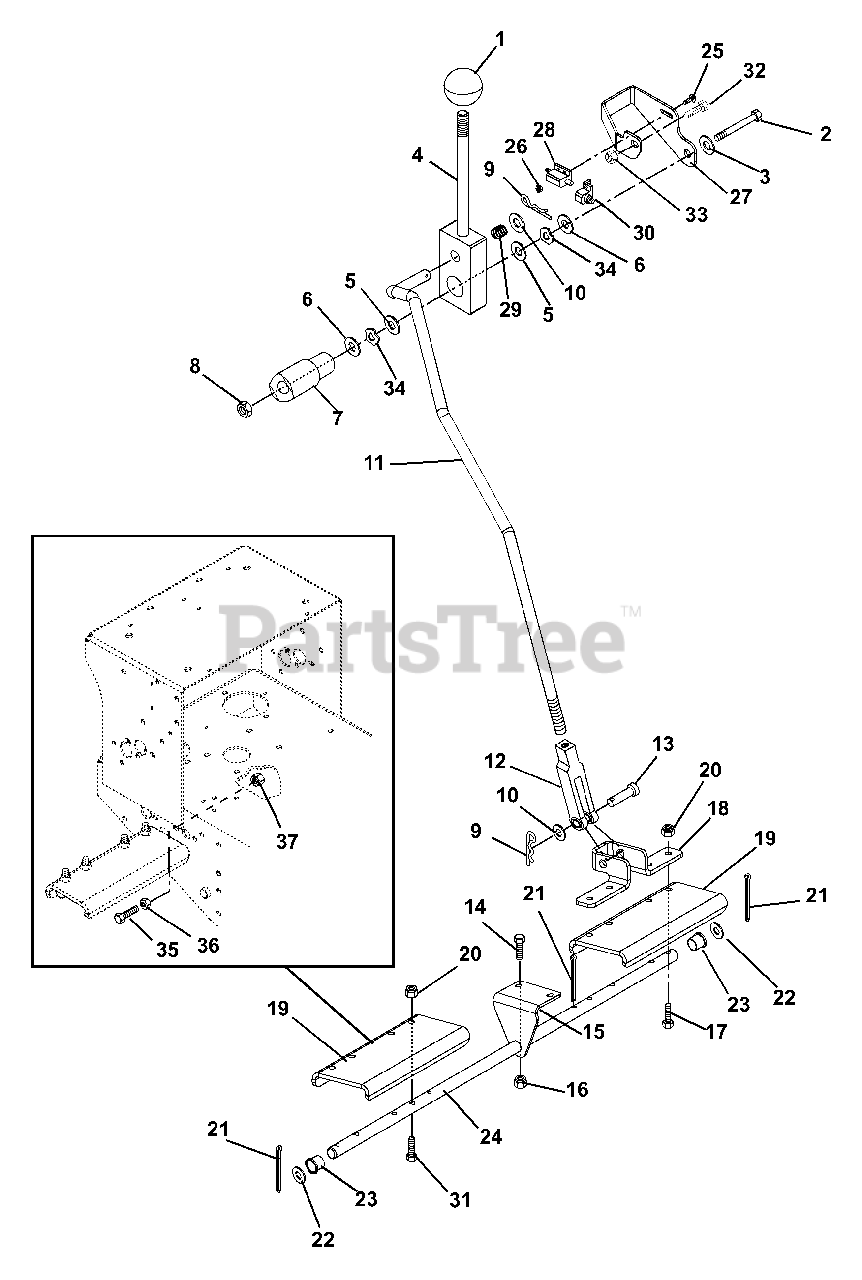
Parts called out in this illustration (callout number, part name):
1	KNOB,BALL -BLACK 1.47" .375-16
2	BLT-HEX .44-14X4.5 GR5 YWZC
3	@WSHR-FL-STL.50X1.25X.083 YWZC
4	WELDMENT- HANDLE
5	WSHR-FL-NYL .760X1.25X.030
6	WSHR-FL-STL.755X1.375X.062YWZC
7	PIVOT, BRAKE
8	@NUT-LK-NYL .44-14 YWZC
9	PIN-HAIR INT .08X.18X1.18 YWZC
10	@WSHR-FL-STL.406X.812X.065 YWZ
11	ROD - BRAKE - HYDRO
12	CLEVIS, .38-24 ADJ.
13	PIN-CLEV .370X1.75
14	@BLT-HEX .38-16X1.00 GR5 YWZC
15	BRACKET, BRAKE SHAFT
16	@NUT-LK-NYL .38-16 YWZC
17	@BLT-HEX .25-20X1.50 GR5 YWZC
18	BRAKE, ARM
19	PAD, BRAKE
20	@NUT-LK-NYL .250-20 YWZC
21	@PIN-CTR .12X1.00 EXTPRSQCT YZ
22	@WSHR-FL-STL.656X1.31X.095 YWZ
23	BSHG-FLG .630X1.000X.625 NY
24	BRAKE, SHAFT
25	@SCR-MCH 10-24X.75 HWH YWZC
26	@NUT-LK-NYL 10-24 W/INSRT YWZC
27	BRACKET - BRAKE SWITCH
28	SWITCH,INTERLOCK
29	SG-COMP .045X.600X.750 WLD7.5
30	BOOT, RUBBER
31	@BLT-HEX .25-20X1.25 GR5 YWZC
32	@BLT-HEX .31-18X.75 GR5 YWZC
33	@NUT-LK-TOP-FLG .31-18 YWZC
34	WASHER-WAVE .760X1.120X.080
35	@BLT-HEX .38-16X1.75 GR5 YWZC
36	@NUT-HEX .38-16 YWZC
37	@NUT-LK-NYL .38-16 YWZC
